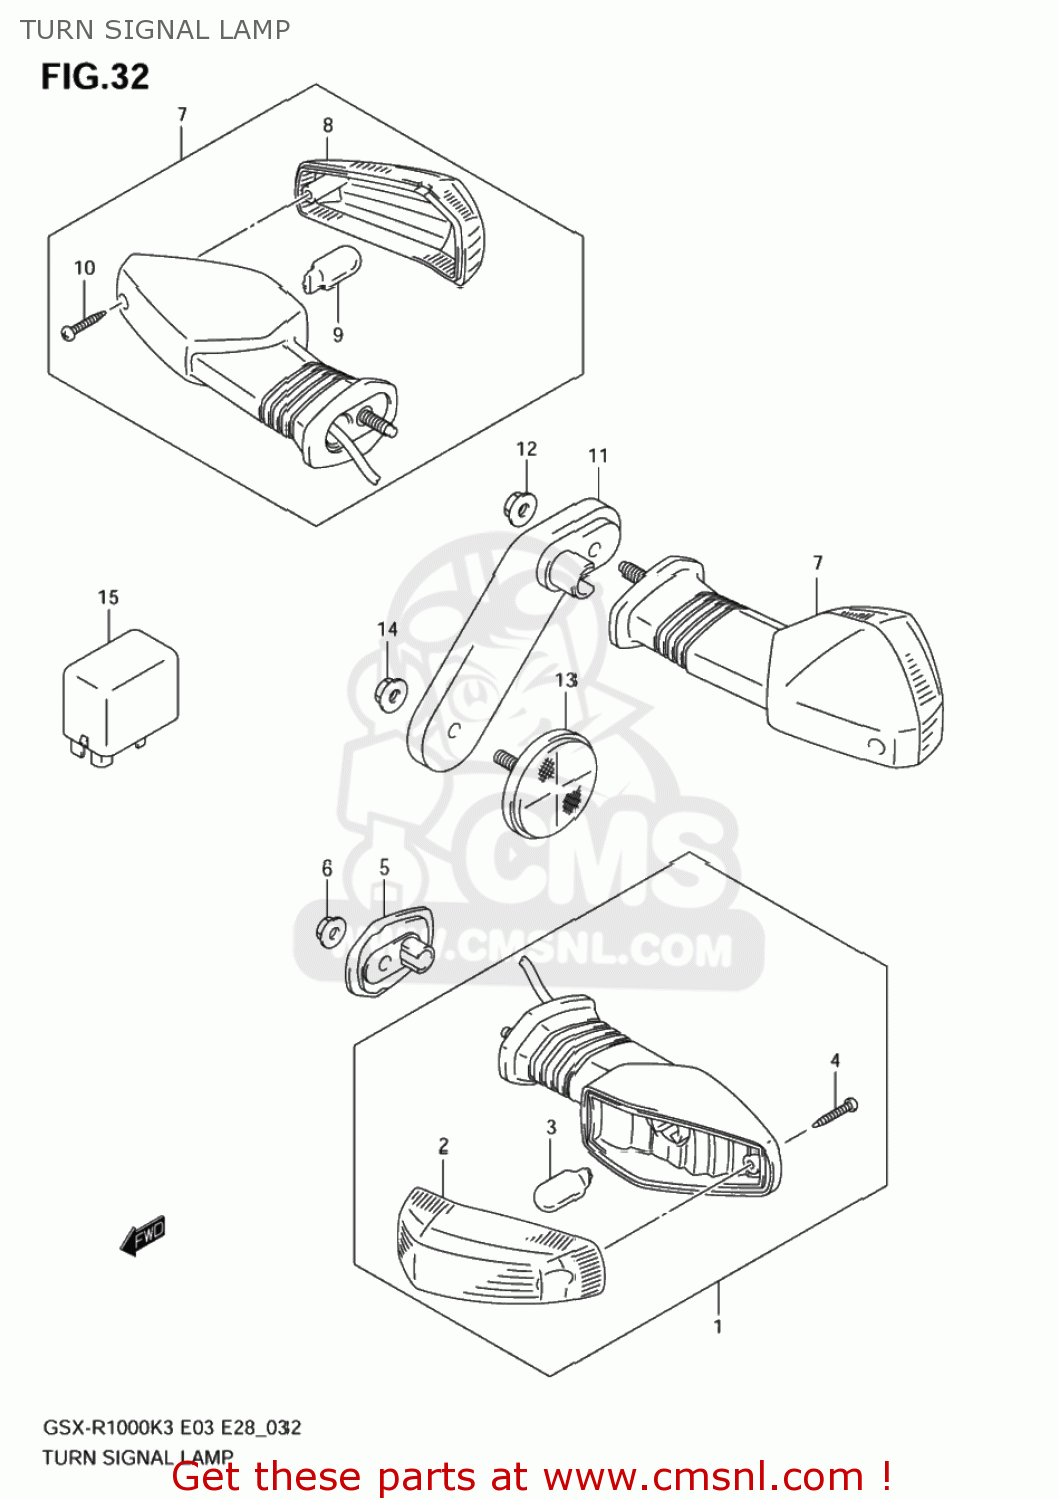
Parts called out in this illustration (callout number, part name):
1	LAMP ASSY,FR TURN SIGNAL,R
2	LENS
3	BULB(12V18W)
4	SCREW
5	PLATE,FR TURNSIGNAL
6	NUT
7	LAMP ASSY,RR TURNSIGNAL,R
8	LENS
9	BULB(12V18W)
10	SCREW
11	PLATE,RR TURN SIGNAL,R
12	NUT
13	REFLECTOR ASSY,RR SIDE
14	NUT
15	RELAY ASSY,TURNSIGNAL
